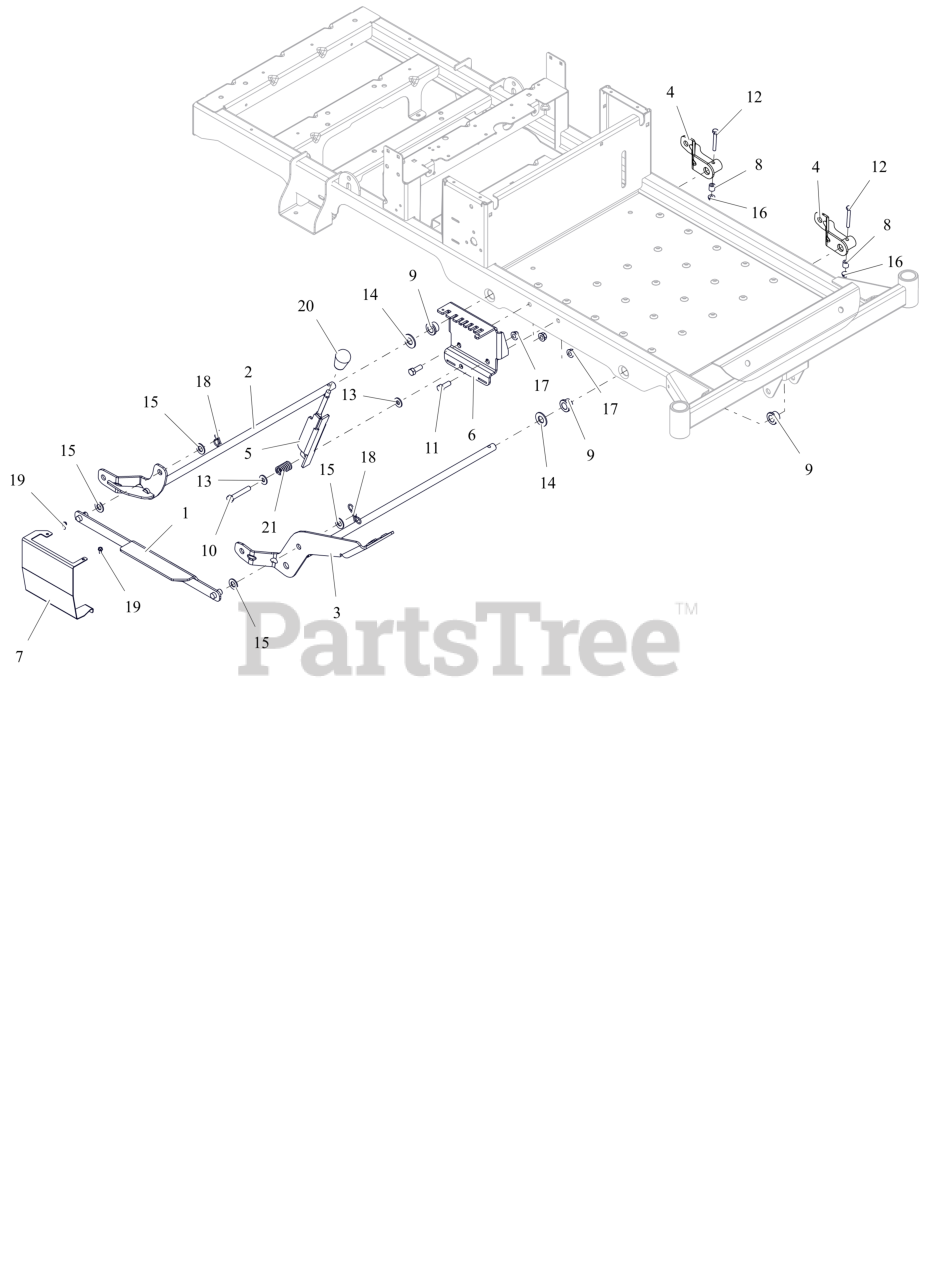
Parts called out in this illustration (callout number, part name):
1	WLDMT, LIFT /HOC LINK (ORANGE)
2	WLDMT, REAR DECK LIFT (ORANGE)
3	WLDMT, FOOTPEDAL (ORANGE)
4	WLDMT, DECK LIFT ARM (ORANGE)
5	WLDMT, HEIGHT OF CUT (ORANGE)
6	PLATE, HEIGHT (ORANGE)
7	GUARD, DECK HOC (ORANGE)
8	BSHG-SLV .265X.500X.500
9	BSHG-FLG .629X.879X.469X1.250
10	BLT,HEX .38-16X2.25 G5 ZCC
11	BLT,HEX .38-16X1.00 G5 ZCC
12	BLT, HEX .25-20X2.00 G5 ZCC
13	WSHR,FLT .375X.875X.083 ZCC
14	WSHR, FLT .656X1.313X.095 ZCC
15	WSHR-FL-NYL .518X1.000X.080
16	NUT-LK-CTR-FLG .25-20 ZC120
17	NUT-LK-CTR-FLG .375-16 GF ZCC
18	PIN, BOWTIE .091X1.875 ZCC
19	SCR,TAP #10-24X.50 HWH TR ZCC
20	KNOB,SOFT TEARDROP,PUSH-ON BLK
21	SPRG, COMPRESSION
